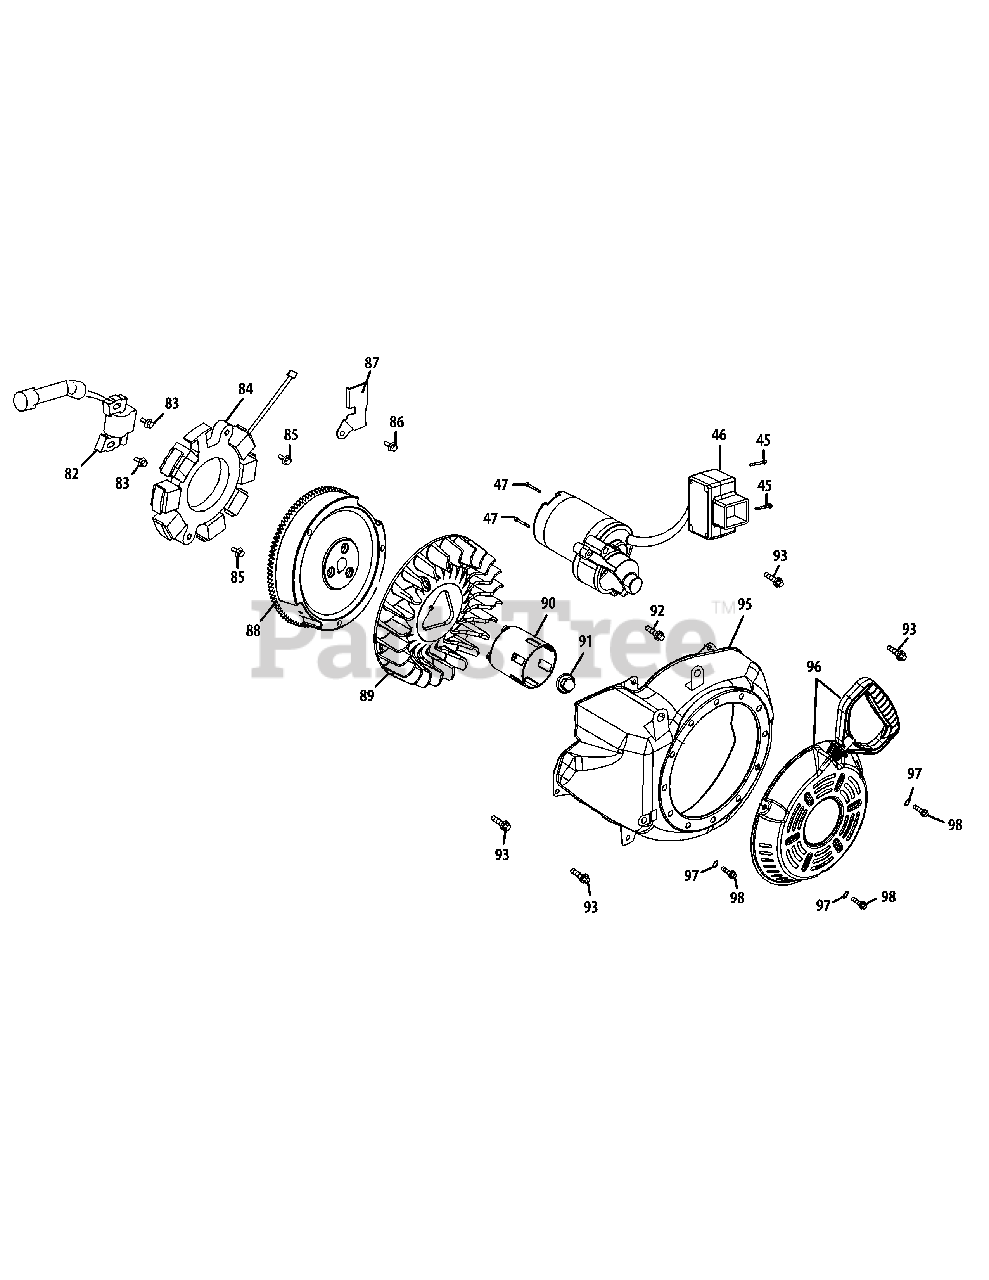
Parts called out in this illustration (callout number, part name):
45	Screw M4 X 55
46	Electric Starter
47	Bolt M8×55
82	Ignition Coil Assembly
83	Ignition Coil Bolt
84	Alternator Assembly
85	Bolt M6×30
86	Bolt M6×8
87	Alternator Wire Clamp Bracket
88	Flywheel
89	Cooling Fan
90	Starter Cup
91	Flywheel Nut, M14×1.5
92	Bolt M6×16
93	Bolt M6×12
95	Blower Housing
96	Recoil Starter Assembly
97	Flat Washer
98	Bolt M6×10
